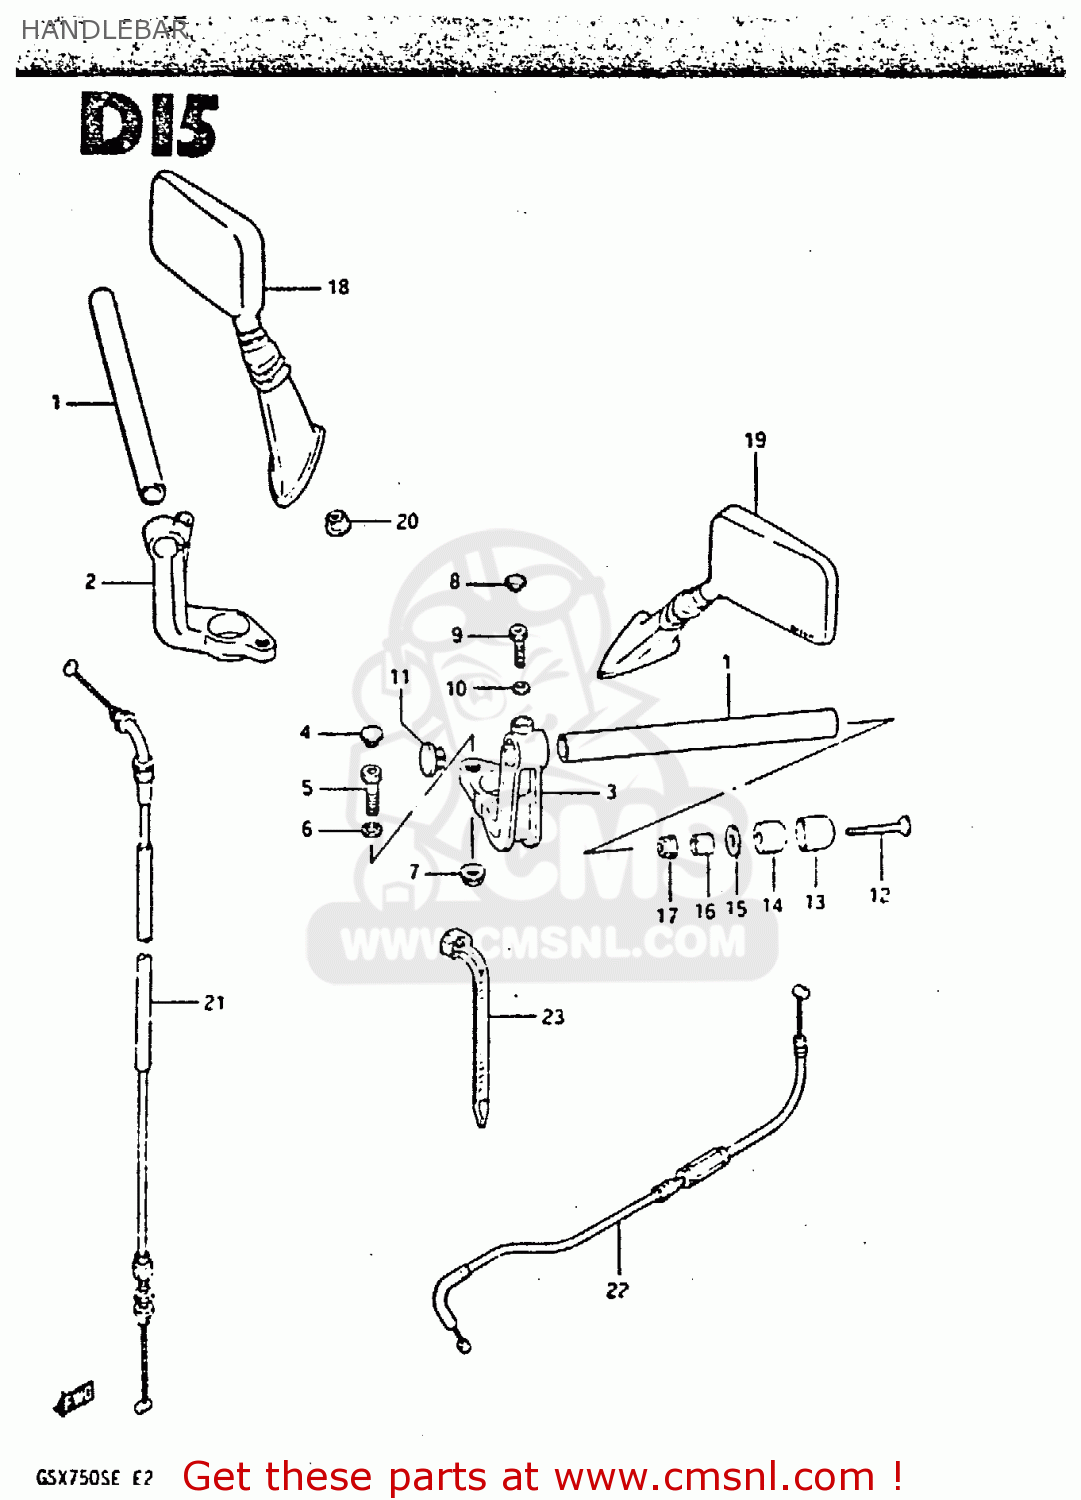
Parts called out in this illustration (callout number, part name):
1	HANDLEBAR
2	HOLDER, RH
3	HOLDER, LH
4	CAP(OD:20)
5	BOLT 10X45
6	WASHER
7	NUT 10MM
8	CAP(OD:14.5)
9	BOLT 8X35
10	WASHER
11	CAP,HANDLEBAR
12	SCREW 6X65
13	CAP,BALANCER
14	BALANCER,HANDLE
15	SPACER,BALANCER
16	EXPANDER,HANDLE BALANCER
17	NUT
18	MIRROR ASSY,RR VIEW,R
19	MIRROR, REAR VIEW LH
20	NUT
21	CABLE, THROTTLE
22	CABLE,CLUTCH
23	CLAMP(L:165)
